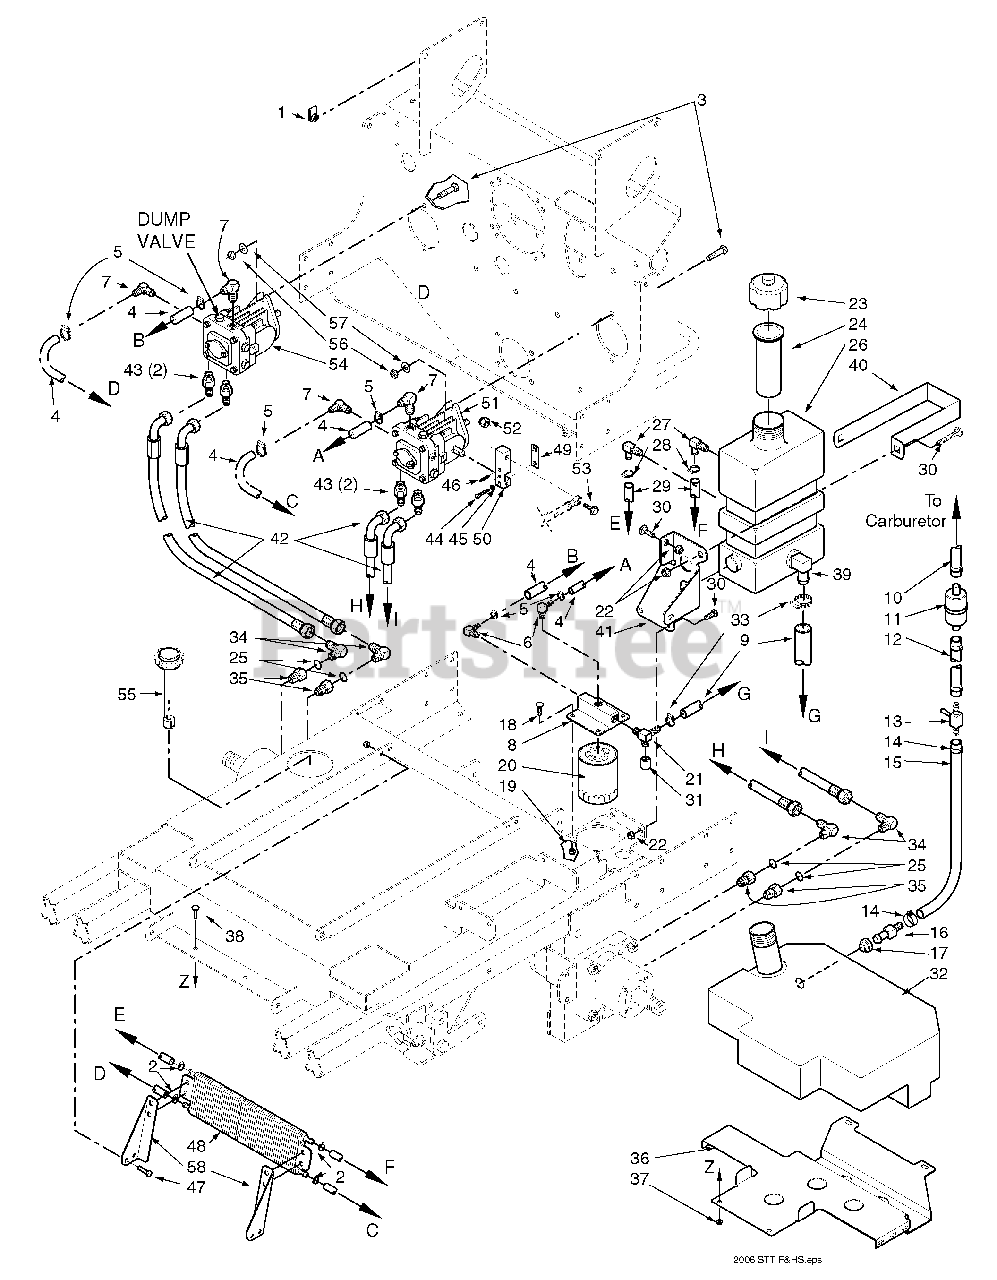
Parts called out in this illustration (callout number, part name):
1	U-Nut 1/4-20
2	Hose Clamp, 0.69" Dia.
3	Bolt, Hex Head 1/4-20 x 2.0"
4	Hose, 3/8" ID Pushlock
5	Clamp, Hose 1/2"
6	Elbow, 90 Degree - 1/4" NPT x 3/8" Hose
7	Elbow, 90 Degree - 9/16" O-Ring x 3/8" Hose
8	Oil Filter Base
9	Hose Assembly, 1/2" ID (Tank to Filter Base)
10	Fuel Hose to Carb.
11	Fuel Filter
12	Fuel Hose, 1/4" ID. Non-Perm.
13	Valve, Shutoff Kawasaki
14	Clamp, Fuel Hose 5/16" Hose I.D.
15	Fuel Hose, 1/4" ID. Non-Perm.
16	Hose Fitting
17	Bushing
18	Bolt, Hex Head 5/16-18 x 1.0" Zinc
19	Nut, Serrated Flange 5/16-18
20	Oil Filter
21	Tee, 3/4" O-Ring x JIC x 1/2" Hose
22	Nut, Hex Elastic Stop 1/4-20
23	Cap, Hydraulic Tank
24	Insert, Filler Neck
25	O-Ring
26	Oil Reservoir Assembly
27	Elbow, 90 Degree .38" Hose
28	Hose Clamp, 0.69" Dia.
29	Hose, 3/8" ID, Pushlock
30	Screw, Phillips Head, 1/4-20
32	Fuel Tank Assembly
33	Clamp, Hose
34	Elbow, 90 Degree, 1/2" x 1/2"
35	Bushing, 7/8"-14 JIC x 3/4"-16 O-Ring
36	Support Bracket, Fuel Tank
37	Nut, 5/16-18 Serrated Flange
38	Bolt, Carraige 1/4-20 x 3/4"
39	Elbow, 90 Degree
40	Strap, Hydraulic Tank
41	Support Bracket, Hydraulic Tank
42	Hose Assembly, Pump
43	Union, 3/4"-16 JIC x 3/4"-16 O-Ring
44	Bolt, Hex Head, 1/4-20 x 1-1/4"
45	Lockwasher, 1/4" Spring
46	Roll Pin, Spring 3/16 x 3/4"
47	Bolt, Hex Head 5/16-18 x 3/4"
48	Cooler, Oil
49	Clamp Plate, Pump Control
50	Block, Pump Control
51	Pump, Left Hand
52	Nut, Hex, Elastic Stop 3/8-16
53	Bolt, Hex Head, 3/8-16 x 1-1/4"
54	Pump, Right Hand
55	Cap, Fuel Tank W/Gauge
56	Nut, Hex Elastic Stop 3/8-16
57	Flatwasher, 3/8" (.391 x .938 x .105") Grade 8
58	Mounting Bracket - LH, Oil Cooler
